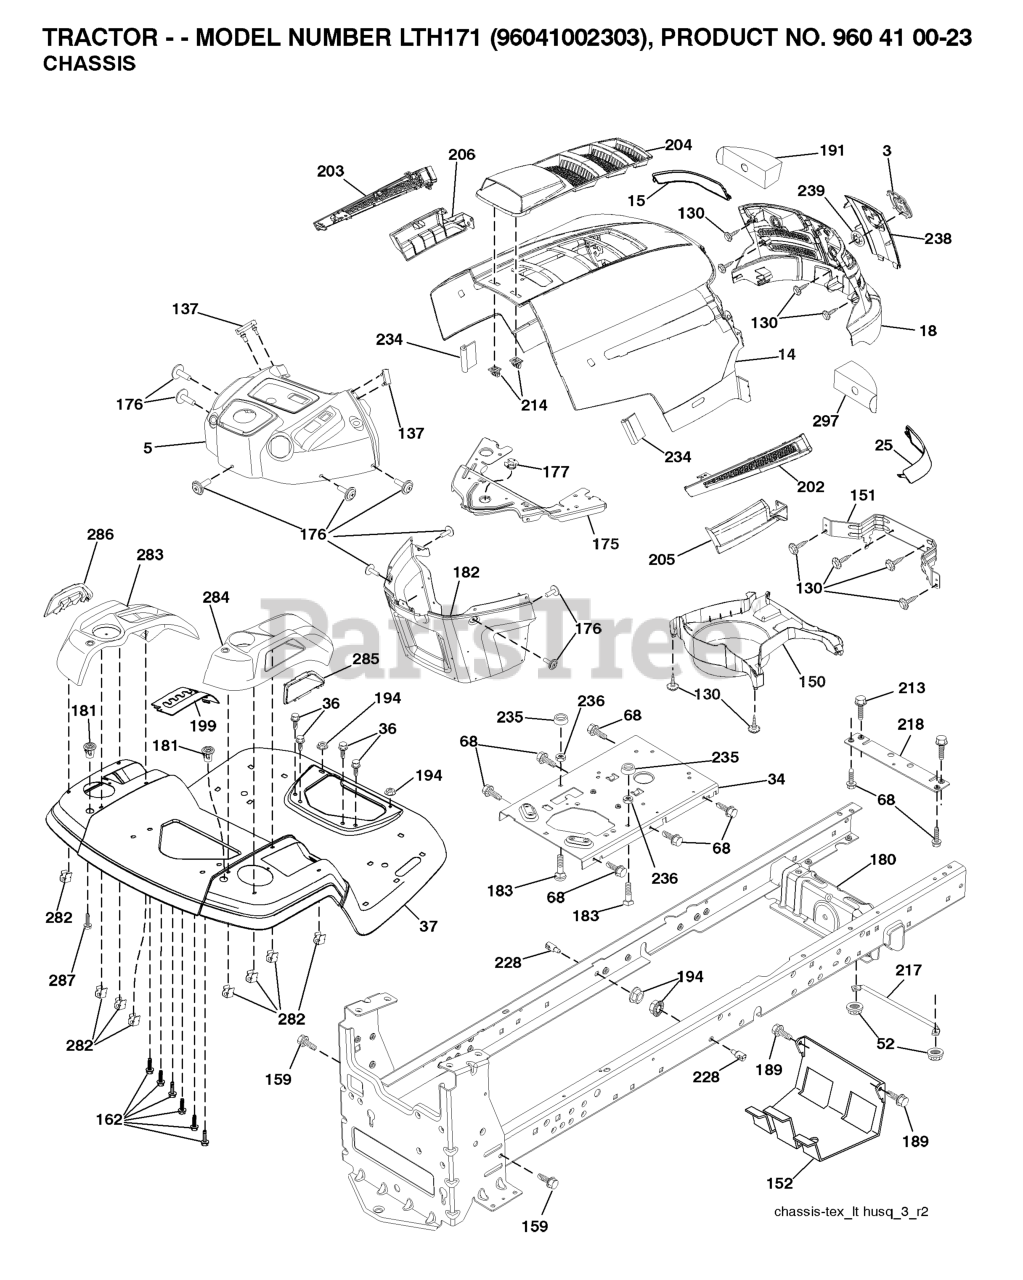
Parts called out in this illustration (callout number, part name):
3	RP LOGO
5	DASH
14	HOOD
15	LENS.HUSQVARNA LT.LH
18	RP GRILLE/LENS ASM.
25	LENS.HUSQVARNA LT.RH
34	PLATE.ENGINE.WELDED.CHASSIS
36	SCREW 5/16"
37	RP FENDER.TLT.FS.W/CPH.422
52	LOCKNUT
68	Screw 5/16-18 x 1/2 Hex, Self Tapping 5/16-18 x 1/2
130	SCREW.#10 X 0.750.BOS
137	BUMPER DASH
151	BRACKET PIVOT
152	SHIELD.BROWNING.W/TEX
159	SCREW, 3/8-16X3/4
162	SCREW.HI-LO.CONSOLE
175	CROSSMEMBER
176	SCREW.#10-24X5/8.RN.QU
177	BUSHING STEERING
180	CHASSIS
181	BUSHING.MNT.FEND.CRGO.
182	DASH.LOWER.PREDATOR LT
183	BOLT.5/16-18X1-1/4 FULL.THREAD
189	SCREW
191	INSERT REFLECTIVE
194	NUT LOCK HEX FLANGE 5/16-18
199	PLATE.DECK.LIFT.HUSQ.LT
202	VENT SIDE HOOD LH
203	VENT SIDE HOOD RH
205	SKIRT SIDE RH
206	SKIRT SIDE LH
213	BOLT
214	CLIP.RETAINER.TINNER.
217	ROD.PIVOT.HOOD
218	X-PIECE.HOOD.STOP.NON/
228	STUD.FASTNER.W/ANTI-ROTATE
234	BUMPER.HOOD.TEX.HUSQVARNA
235	SPACER FENDER
236	NUT.CENTERLOCK.5/16-
238	TRIM
282	CLIP.RETAINER.CONSOLE.LT.HUSQ
283	CONSOLE.DECK.LIFT.HUSQ.N/FR.GR
284	CONSOLE.SHFT.HYD,HUSQL
285	CONSOLE INSERT RH
286	CONSOLE.INSRT.LH.HUSQ.LT.BLACK
287	SCREW 1/4X20
297	INSERT.REFLECTIVE.RH.
